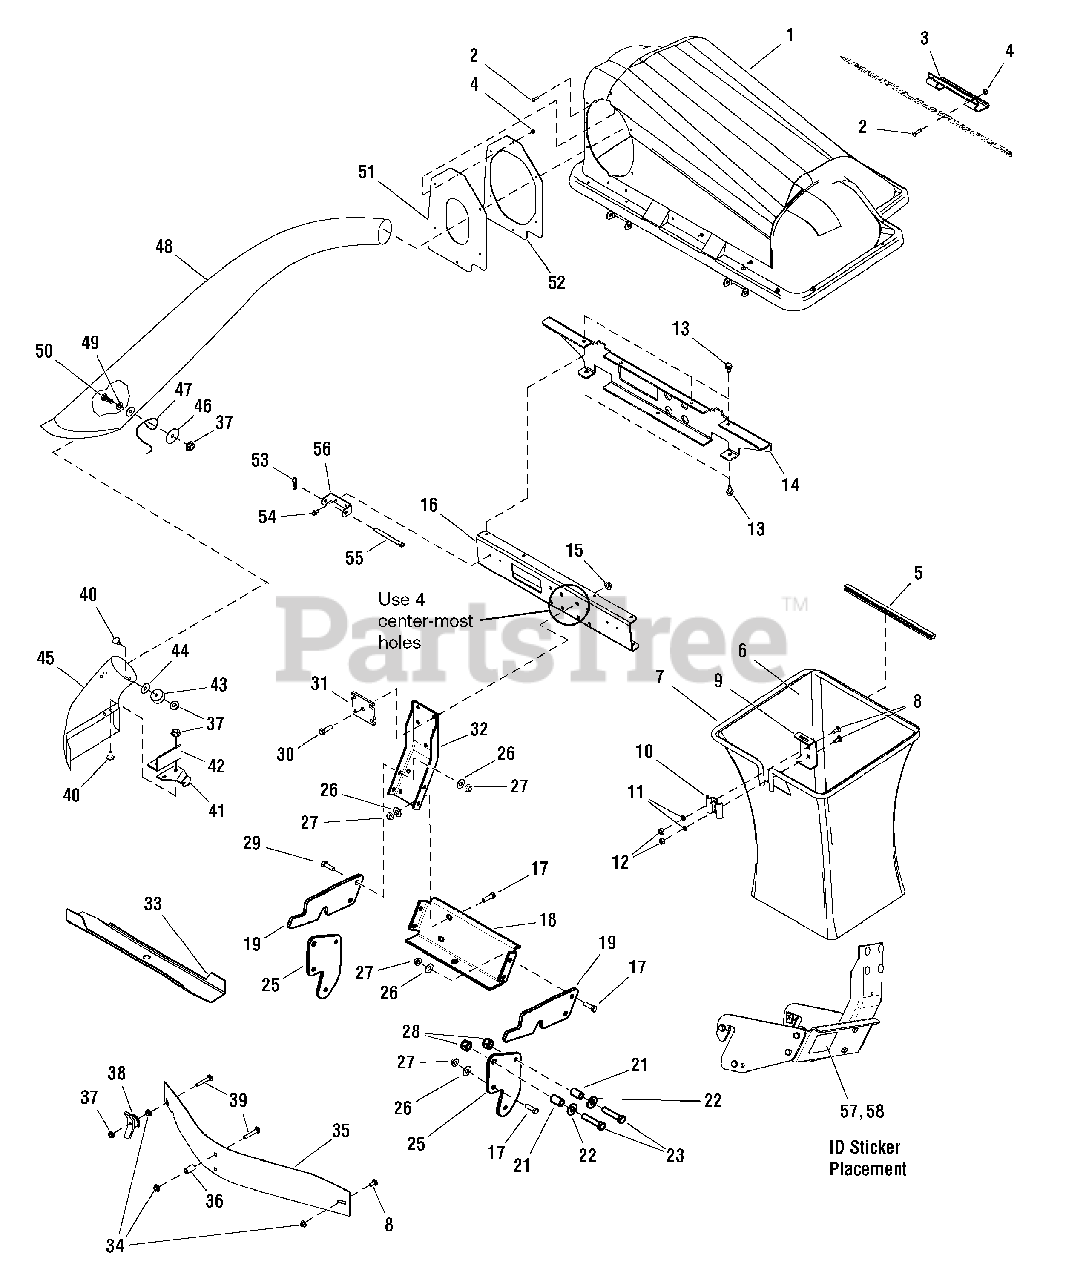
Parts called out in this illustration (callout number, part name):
1	COVER ASSEMBLY, Twin Catcher
2	SCREW, Truss Head Phillips, 10-24 x 3/4
3	HANDLE, Plastic
4	NUT, Hex Lock w/Nylon Insert, 10-24
5	CLIP, Tube Grass Bag
6	BAG, Grass White Poly
8	BOLT, Carriage, 5/16-18 x 3/4
9	HANGER, Grass Bag
10	CLAMP, Grass Bag Plain
11	LOCKWASHER, Spring, 5/16
12	NUT, Hex, 5/16-18
13	SCREW, Hex Washer Head Taptite, 5/16-18 x 3/4
14	BRACKET, Tab Cross Support Twin
15	NUT, Hex Whiz Lock Flange
16	CHANNEL, Cross Support Twin
17	CAPSCREW, Hex Head, 5/16-18 x 1
18	BRACKET, Lower
19	SUPPORT, Side Hitch
21	SPACER, 1/2 ID x 1-17/64
22	WASHER, 1/2 x 1-1/4 OD
23	CAPSCREW, Hex Head, 1/2-13 x 2-1/2
25	PLATE, Side
26	LOCKWASHER, Spring, 3/8
27	NUT, Hex, 3/8-16
28	NUT, Hex Locking, 1/2-13
29	CAPSCREW, Hex Head, 3/8-16 x 1-1/4, G5
30	CAPSCREW, Hex Head Whiz Lock, 3/8-16 x 1
31	PLATE, Reinforcement, Upright
32	SUPPORT, Upright
33	BLADE, 22.30"
34	NUT, Hex Flange Locking, 5/16-18
35	BAFFLE, 38"
36	SPACER, 3/8 ID x 5/8 OD x 1-5/32
37	NUT, Hex Flange Two Way Locking, 5/16-18
38	WINGNUT ASSEMBLY
39	BOLT, Carriage, 5/16-18 x 2-1/4, G5
40	CAPSCREW, Hex Head, 5/16-18 x 3/4
41	BRACKET, Offset
42	BRACKET, Deflector Prop
43	WASHER, 11/32 x 1-3/4 OD
44	WASHER, 5/16 x 1-1/2
45	ADAPTER, 38" Mower
46	WASHER, 5/16 x 2-1/8
47	LATCH, Tube
48	TRANSFER TUBE
49	WASHER, 5/16 x 3/4 OD
50	CAPSCREW, Hex Head, 5/16-18 x 3/4
51	SEAL, Cover
52	FLANGE, Seal
53	CLIP, Hairpin, 5/8 Long
54	CAPSCREW, Hex Washer Head, Taptite, 1/4-20 x 1/2
55	PIN, Cover Hinge
56	PIVOT, Hinge
57	ID LABEL/SERIAL PLATE
58	OVERLAY, Mylar
